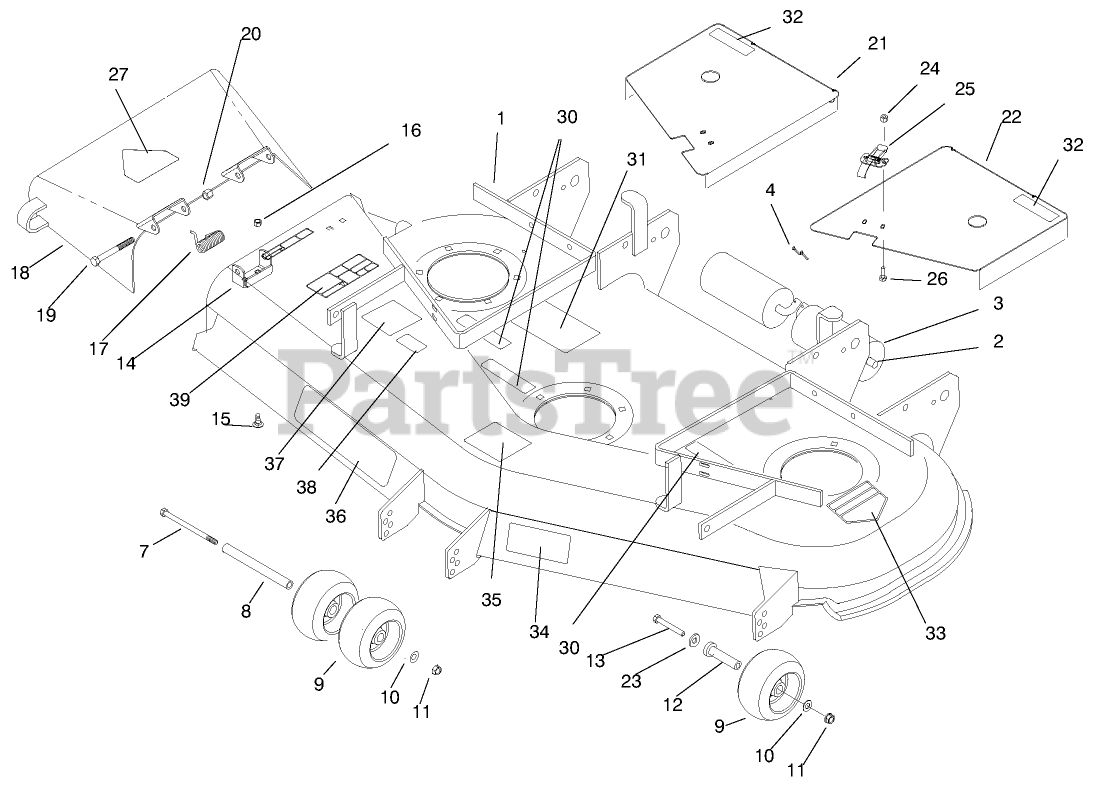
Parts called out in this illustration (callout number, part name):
1	Deck/Decal ASM
2	SHAFT-ROLLER, REAR
3	ROLLER-DECK
4	PIN-COTTER
7	SCREW-HH
8	SPACER-WHEEL
9	WHEEL-GAGE
10	WASHER-FLAT
11	NUT-LOCK, NI
12	SPACER-WHEEL
13	SCREW-HH
14	BRACKET-PIVOT
15	SCREW-CARR
16	NUT-LOCK, CONE
17	SPRING
18	DEFLECTOR ASM, 52" W/DECAL
19	SCREW-HH
20	NUT-HEX
21	COVER ASM-RH
22	LH COVER ASM
23	WASHER-BELLEVILLE
24	NUT-LOCK, FLANGE
25	CLAMP-SLOTTED
26	SCREW-HWH
27	DECAL-DANGER
29	DECAL-DANGER
30	DECAL-COVER, MISSING
31	DECAL BELT INSTALLATION
32	DECAL-DANGER
33	DECAL-DANGER
34	DECAL-TORQUE, BLADE BOLT
35	DECAL-WHEEL, GAGE
36	DECAL
37	DECAL - SAFETY
38	DECAL
39	DECAL-DANGER, THROWN OBJECT
